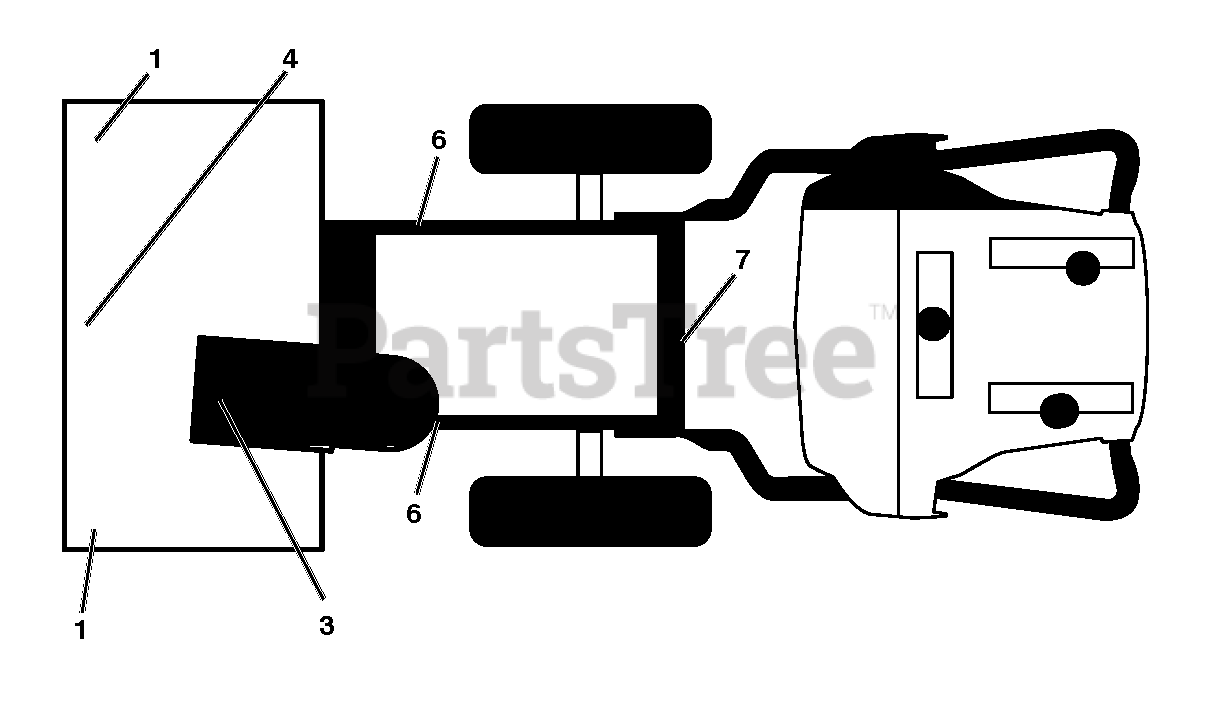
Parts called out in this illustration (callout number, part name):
1	DECAL.AUGER.SAFETY.
3	DECAL.CHUTE.SAFETY.EU/SC.17
4	DECAL.AUGER."
6	DECAL.NOISE.LEV.105/CE.EAC.UKR
7	DECAL.NOISE.LEV.105/CE.EAC.UKR
